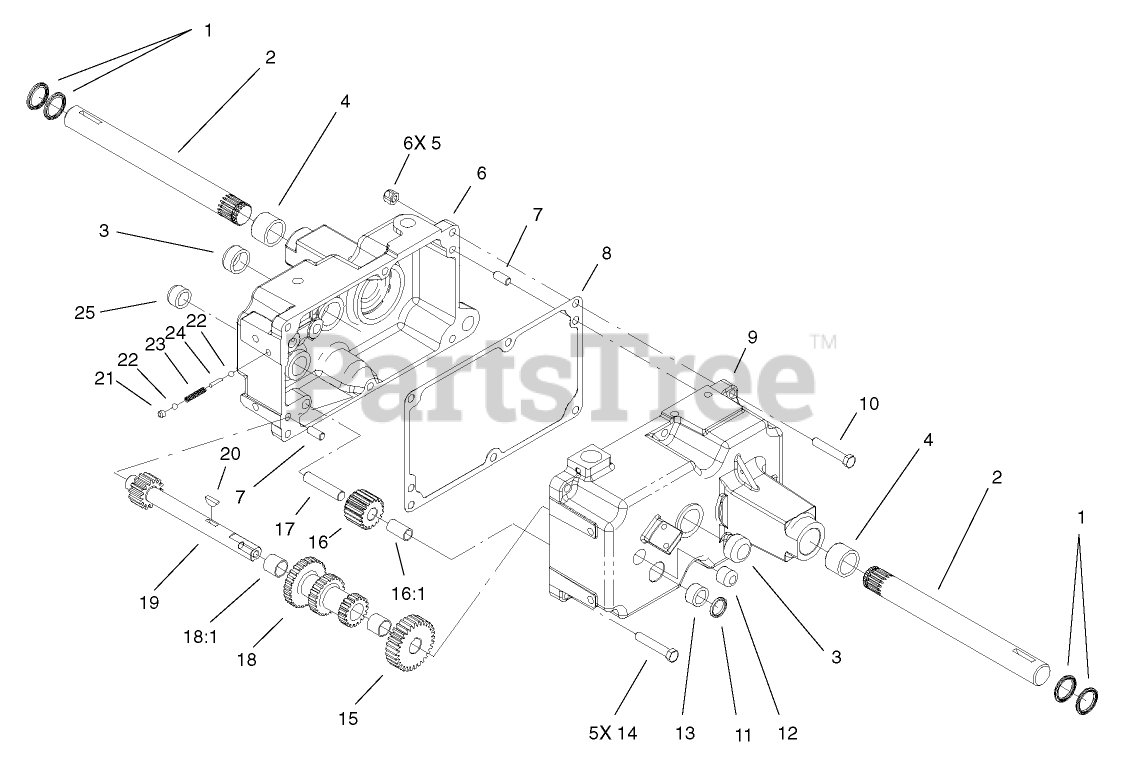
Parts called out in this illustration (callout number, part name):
1	SEAL-OIL
2	AXLE-REAR
3	BEARING-NEEDLE
4	BEARING
5	NUT-LOCK, NI
6	CASE-RH TRANS
7	PIN-DOWEL
8	GASKET-TRANSMISSION
9	CASE-TRANS LH
10	SCREW-HH
11	SEAL-OIL
13	BEARING-NEEDLE
14	SCREW-HH
15	GEAR-CLUSTER SHAFT
16	GEAR/BUSHING ASM-REVERSE IDLER
17	PIN-DIFFERENTIAL
18	GEAR-CLUSTER
19	SHAFT-CLUSTER
20	KEY-WOODRUFF
21	CUP-PLUG
22	BALL-DETENT
23	SPRING-SHIFT STOP
24	PIN-SHIFT
25	BEARING-NEEDLE
